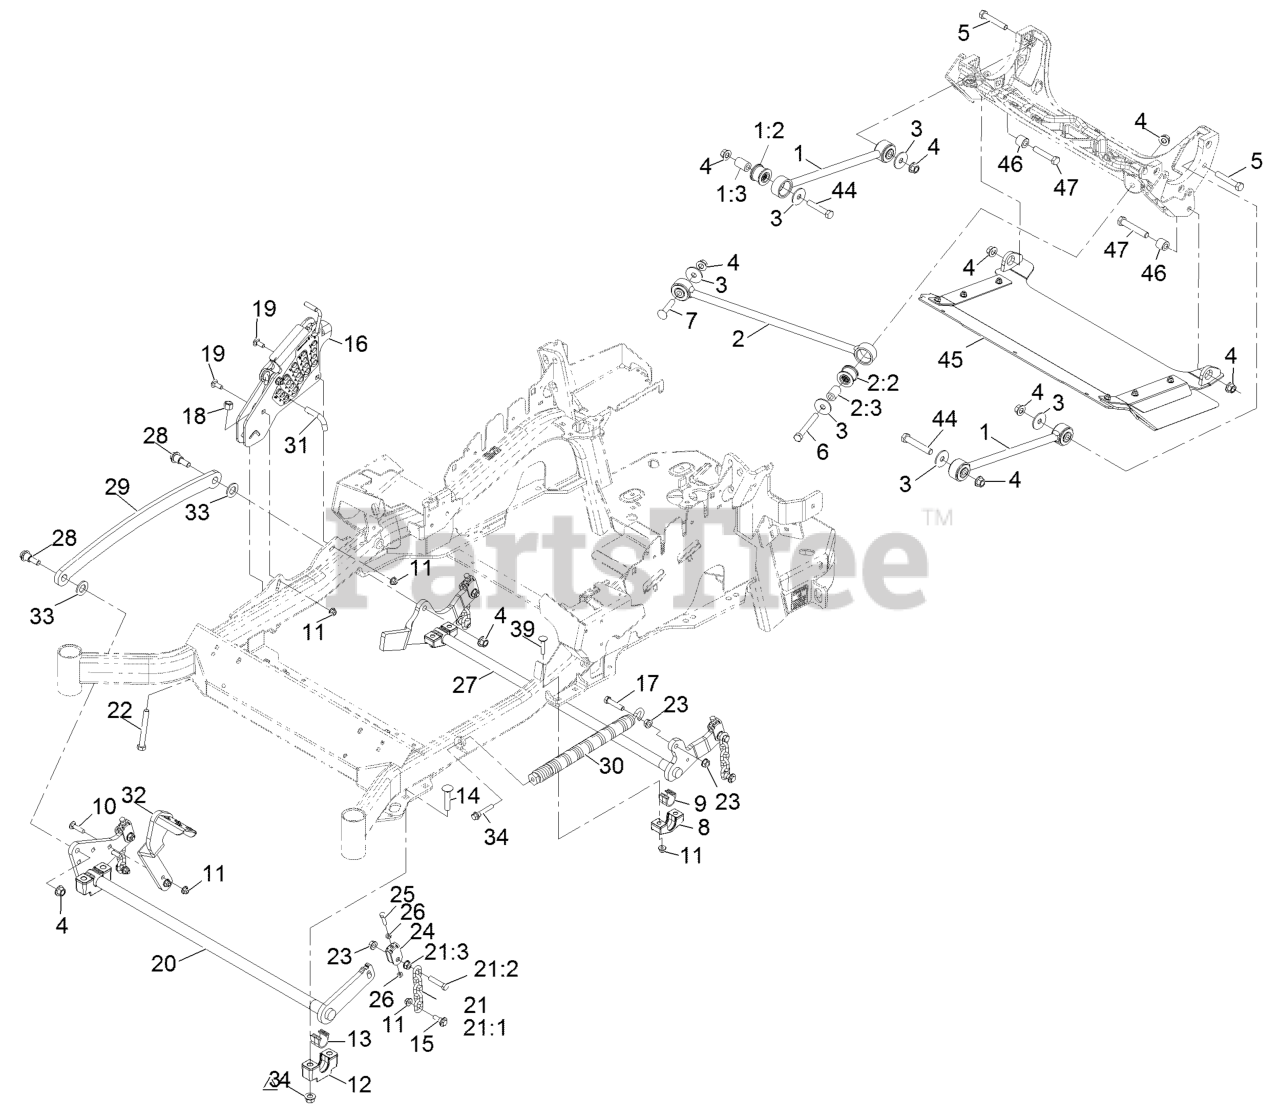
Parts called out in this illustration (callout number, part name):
1	DECK STRUT ASM
1:2	BUSHING-SUSPENSION, RUBBER
2	PANHARD ROD ASM
2:2	BUSHING-SUSPENSION, RUBBER
3	WASHER-THRUST
4	Nut-Lock 1/2-13
5	SCREW-HH
6	SCREW-HH
7	SCREW-CARR
9	BEARING-CROSS SHAFT, REAR
10	SCREW-CARR
11	NUT-HF, NI
12	SUPPORT-CROSS SHAFT, BEARING
13	BEARING-CROSS SHAFT, FRON
14	Bolt-Carriage 1/2-13 X 2 1/2 Spl Neck
15	SCREW-SHOULDER, HHF
16	HOC ASM
17	SCREW-HH
18	NUT-LOCK, NI
19	BOLT-CARR
20	DECKLIFT-FRONT
21	DECK LIFT CHAIN ASM
21:1	CHAIN-LIFT, DECK
21:2	SCREW-HH
22	BOLT-TAP
24	YOKE-ADJUST, DECK
25	SCREW-HH
26	NUT-JAM
27	LIFT-DECK, REAR
28	SCREW-SHOULDER, HHF 1/2-13 X 1.12
29	LINK-LIFT, DECK
30	SPRING-EXTENSION
31	PIN-HOC
32	LEVER-FOOT
33	WASHER-FLAT
34	BOLT-SHOULDER
39	SCREW-CARR
44	SCREW-HH
46	BUSHING-SLEEVE
47	SCREW-HH
